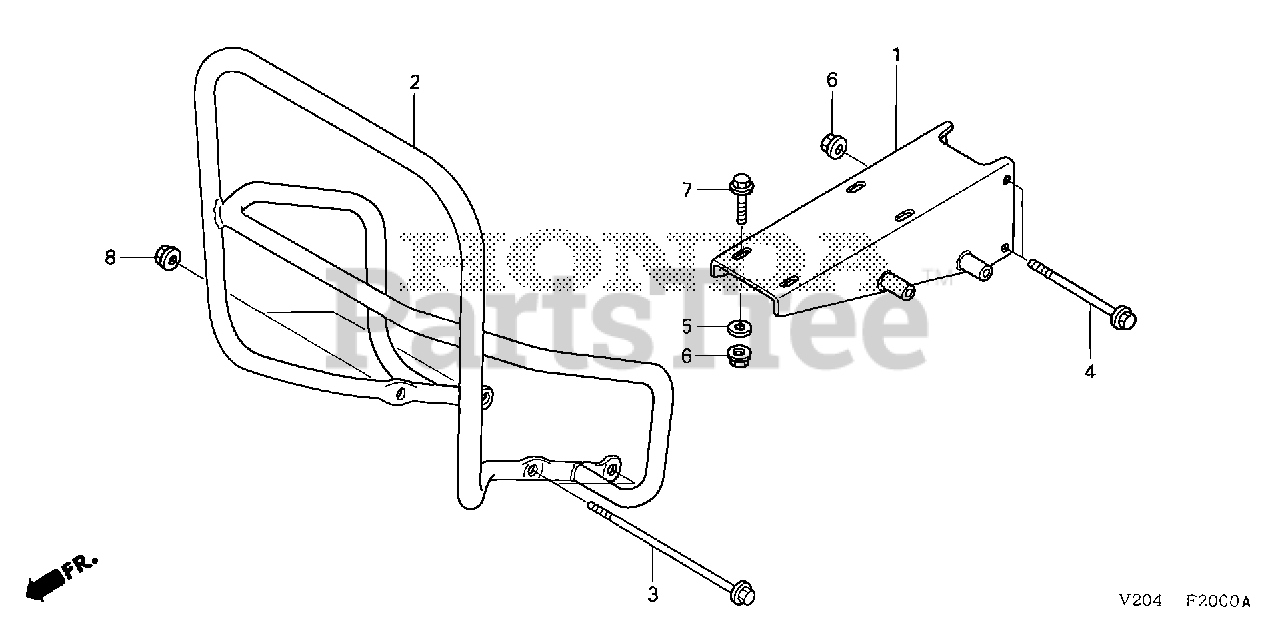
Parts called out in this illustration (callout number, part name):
1	BED, ENGINE *NH105* (MAT BLACK)
2	GUARD, FR. *NH105* (MAT BLACK)
3	BOLT, FLANGE (10X240)
4	BOLT (10X145)
5	WASHER (10.2X20)
6	NUT, FLANGE (10MM)
7	BOLT, FLANGE (10X40)
8	NUT, AXLE (10MM)
